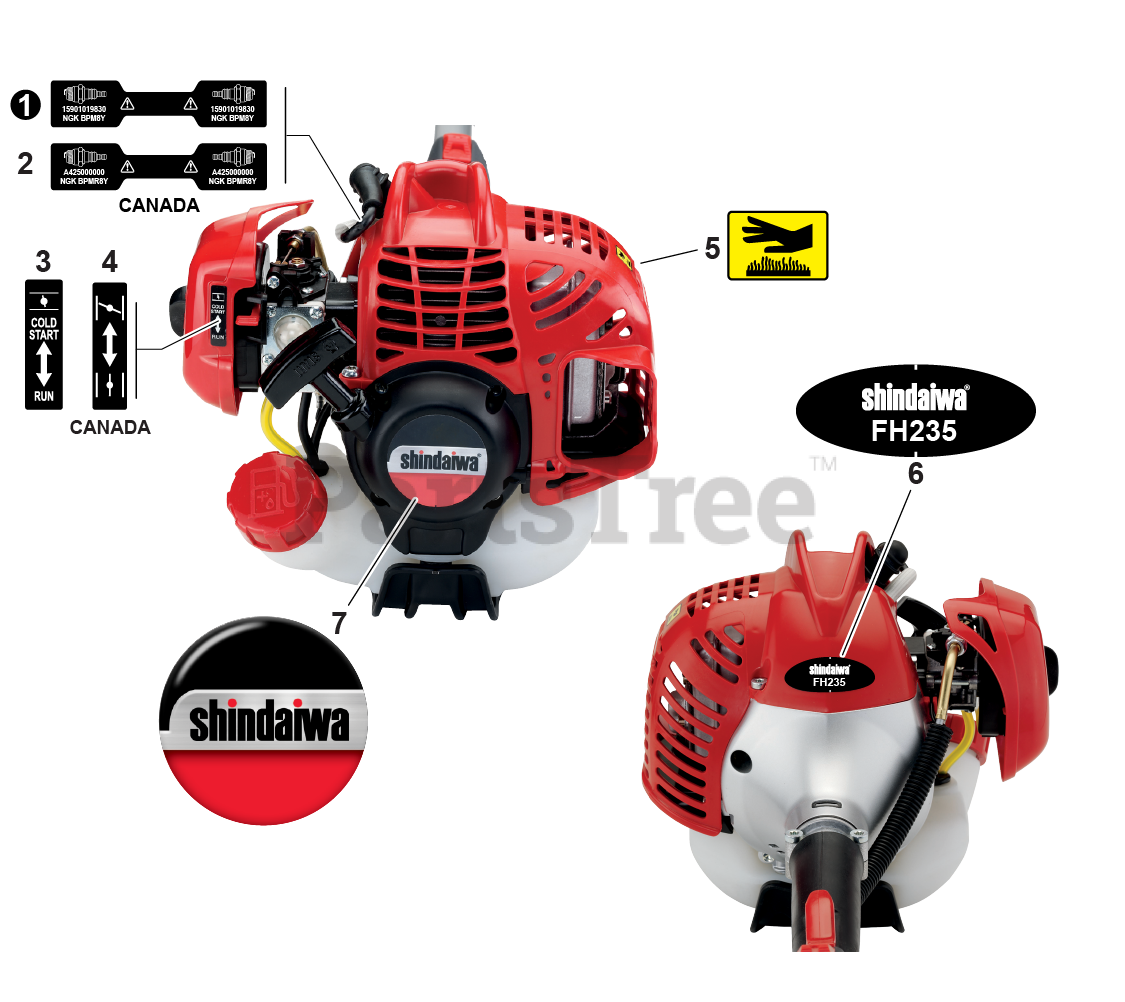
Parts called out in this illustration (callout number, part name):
1	LABEL - SPARK PLUG - BPM8Y
2	LABEL - SPARK PLUG - BPMR8Y
3	LABEL - CHOKE
4	LABEL - CHOKE
5	LABEL - CAUTION - HOT
6	LABEL - MODEL FH235
7	LABEL - SHINDAIWA
